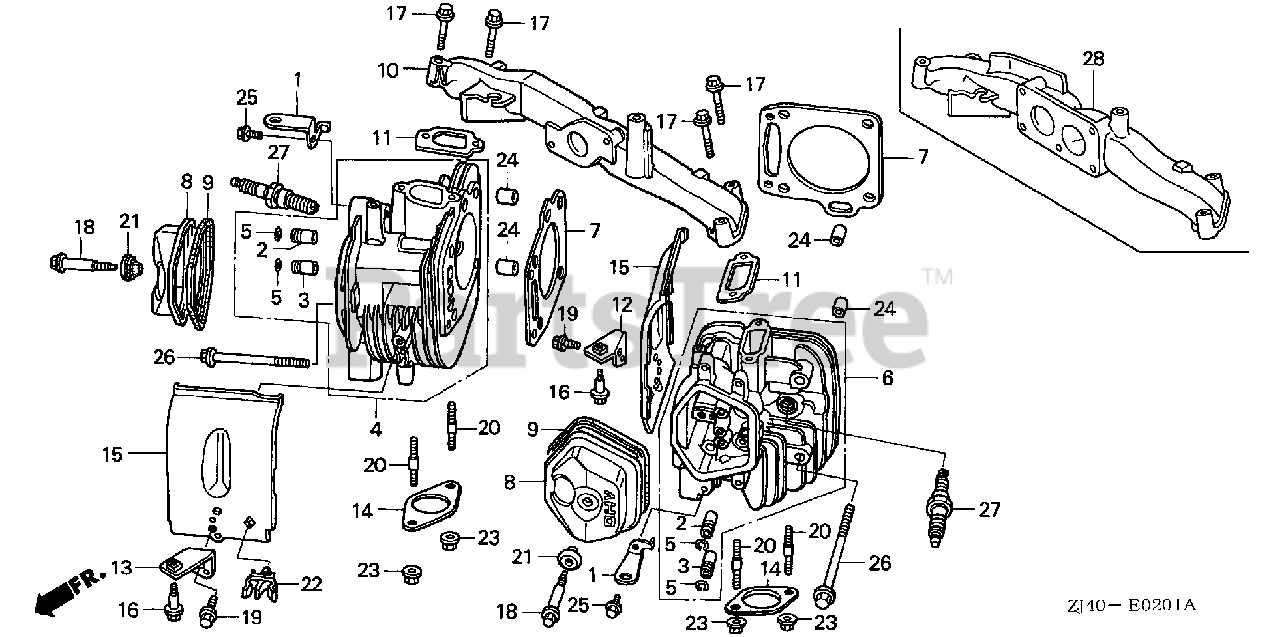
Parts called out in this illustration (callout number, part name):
1	HANGER, ENGINE
2	GUIDE, VALVE (OVER SIZE)
3	GUIDE, EX. VALVE (OVER SIZE)
4	CYLINDER HEAD (#1)
5	CLIP, VALVE GUIDE
6	CYLINDER HEAD (#2)
7	GASKET, CYLINDER HEAD
8	COVER, HEAD
9	GASKET, HEAD COVER
10	MANIFOLD, IN.
11	GASKET, IN. MANIFOLD
12	BRACKET, R. AIR CLEANER
13	BRACKET, L. AIR CLEANER
14	GASKET, EX. PIPE
15	SHROUD, HEAD
16	BOLT, FLANGE (6MM)
17	BOLT, SOCKET (8X45)
18	BOLT, HEAD COVER
19	BOLT, FLANGE (6X14) (CT200)
20	BOLT, STUD (8X22)
21	WASHER, HEAD COVER
22	CLIP, FUEL TUBE
23	NUT, FLANGE (8MM)
24	PIN, DOWEL (12X20)
25	BOLT, FLANGE (8X20)
26	BOLT, FLANGE (10X80)
27	SPARK PLUG (BPR2ES) (NGK)
27	SPARK PLUG (J14CR-U) (DENSO)
27	SPARK PLUG (ZGR4A)
27	SPARK PLUG (J16CR-U) (DENSO)
27	SPARK PLUG (ZGR5A)
